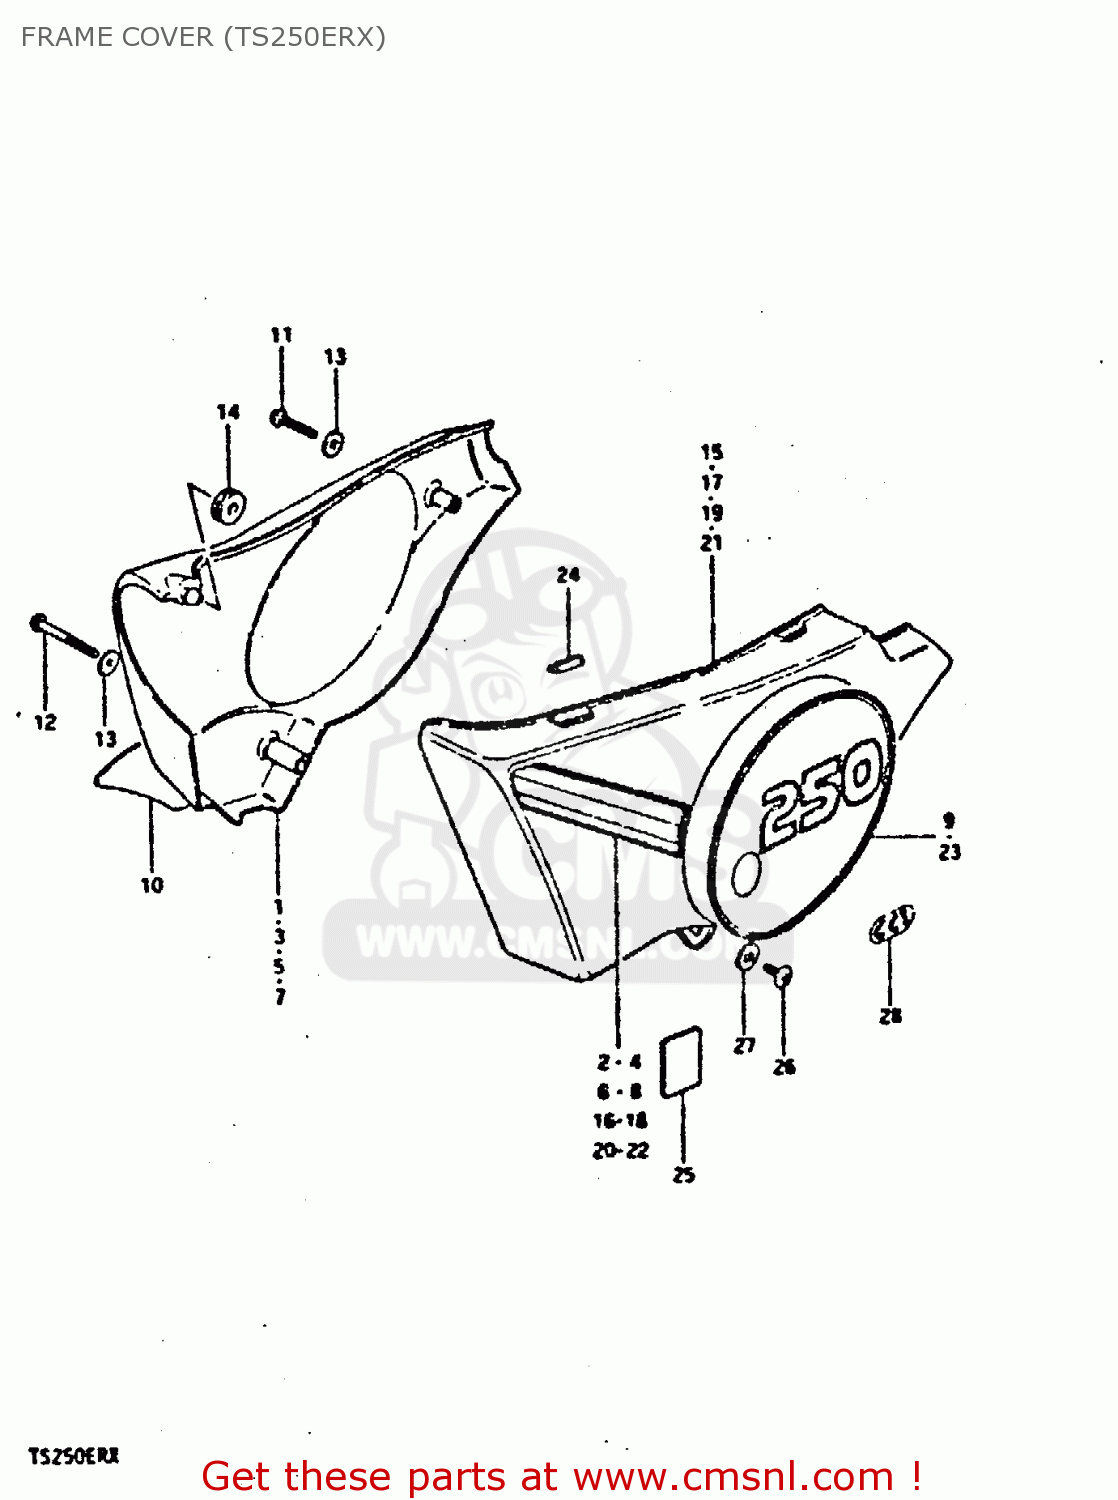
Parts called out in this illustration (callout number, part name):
1	COVER,FRAME,RIGHT
2	TAPE, RH
3	COVER, FRAME RH (RED)
4	TAPE, RH
5	COVER, FRAME RH (YELLOW)
6	TAPE, RH
7	COVER, FRAME RH (WHITE)
8	TAPE, RH
9	EMBLEM, "250" RH (WHITE)
10	EMBLEM,FRAME COVER,RIGHT
11	SCREW
12	SCREW
13	WASHER (6.5*18*1.6)
14	CUSHION
15	COVER,FRAME,LEFT
16	TAPE, LH
17	COVER, FRAME LH (RED)
18	TAPE, LH
19	COVER, FRAME LH (YELLOW)
20	TAPE, LH
21	COVER, FRAME LH
22	TAPE, LH
23	EMBLEM, "250" LH (WHITE)
24	CUSHION,FRAME COVER
25	PROTECTOR(170X95X3.0)
26	SCREW
27	WASHER
28	EMBLEM,CCIS
